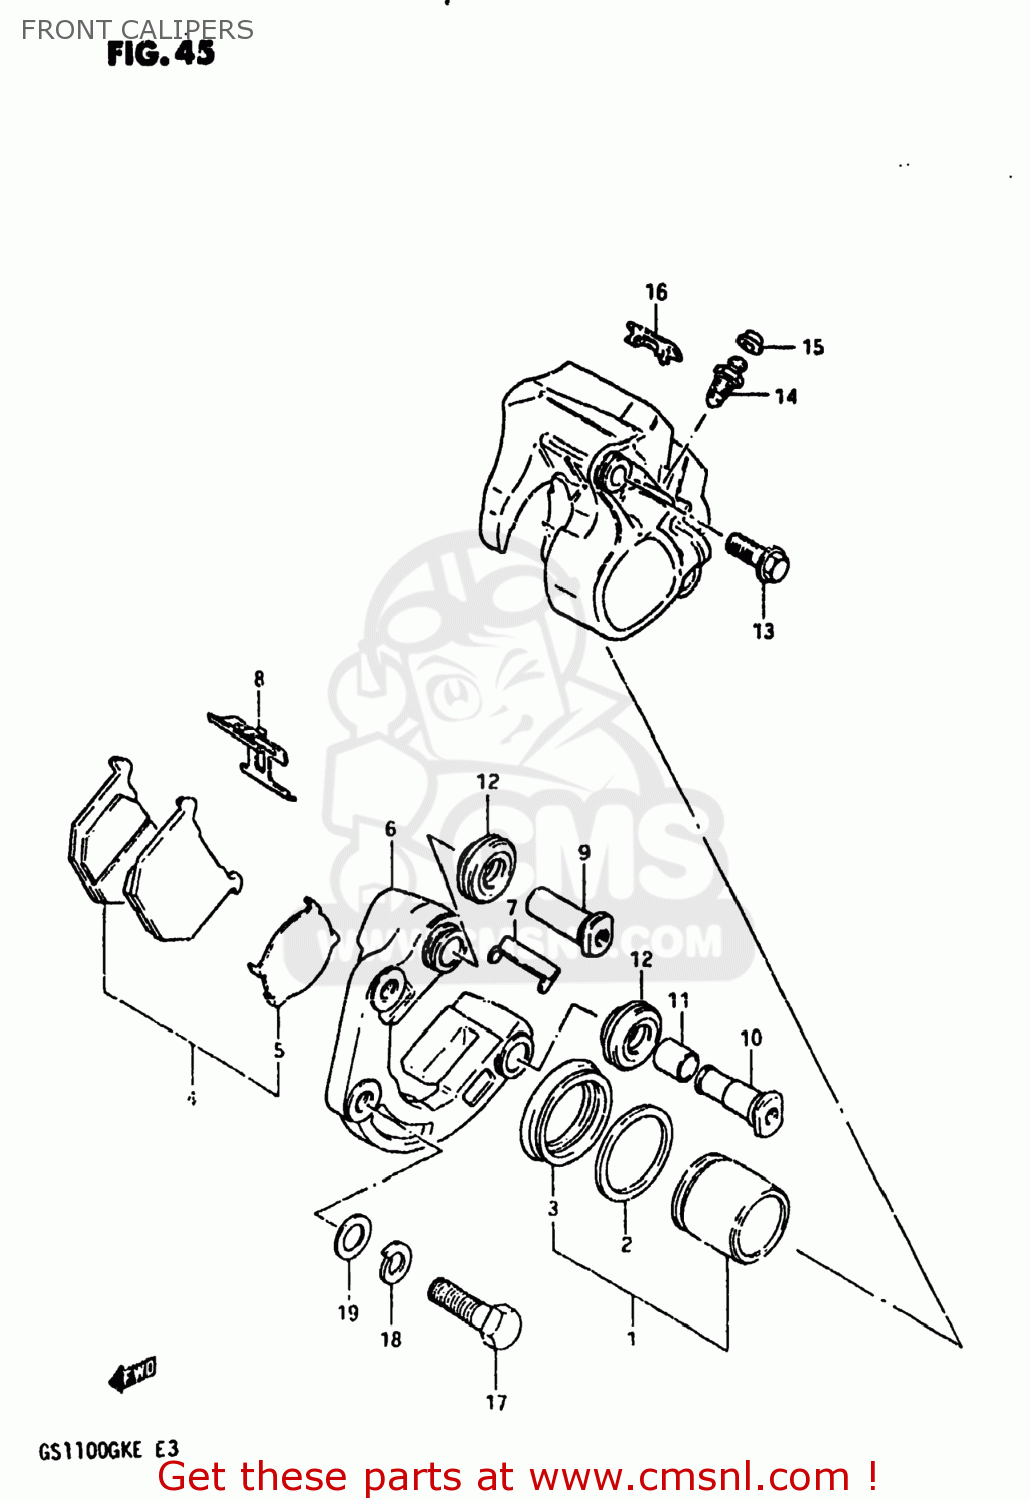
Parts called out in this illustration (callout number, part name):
0	CALIPER ASSY R
1	PISTON SET
2	SEAL,FR CALIPE
3	BOOT,PISTON
4	PAD SET,BRAKE (MCA)
5	SHIM,PAD
6	CARRIER,CALIPER,LEFT
7	GUIDE,PAD
8	SPRING,PAD
9	AXLE NO.1
10	AXLE NO.2
11	BUSH,AXLE
12	BOOT,AXLE
13	BOLT
14	BLEEDER
15	CAP,BREATHER
16	COVER
17	BOLT 10X53.5
18	LOCK WASHER
19	WASHER
